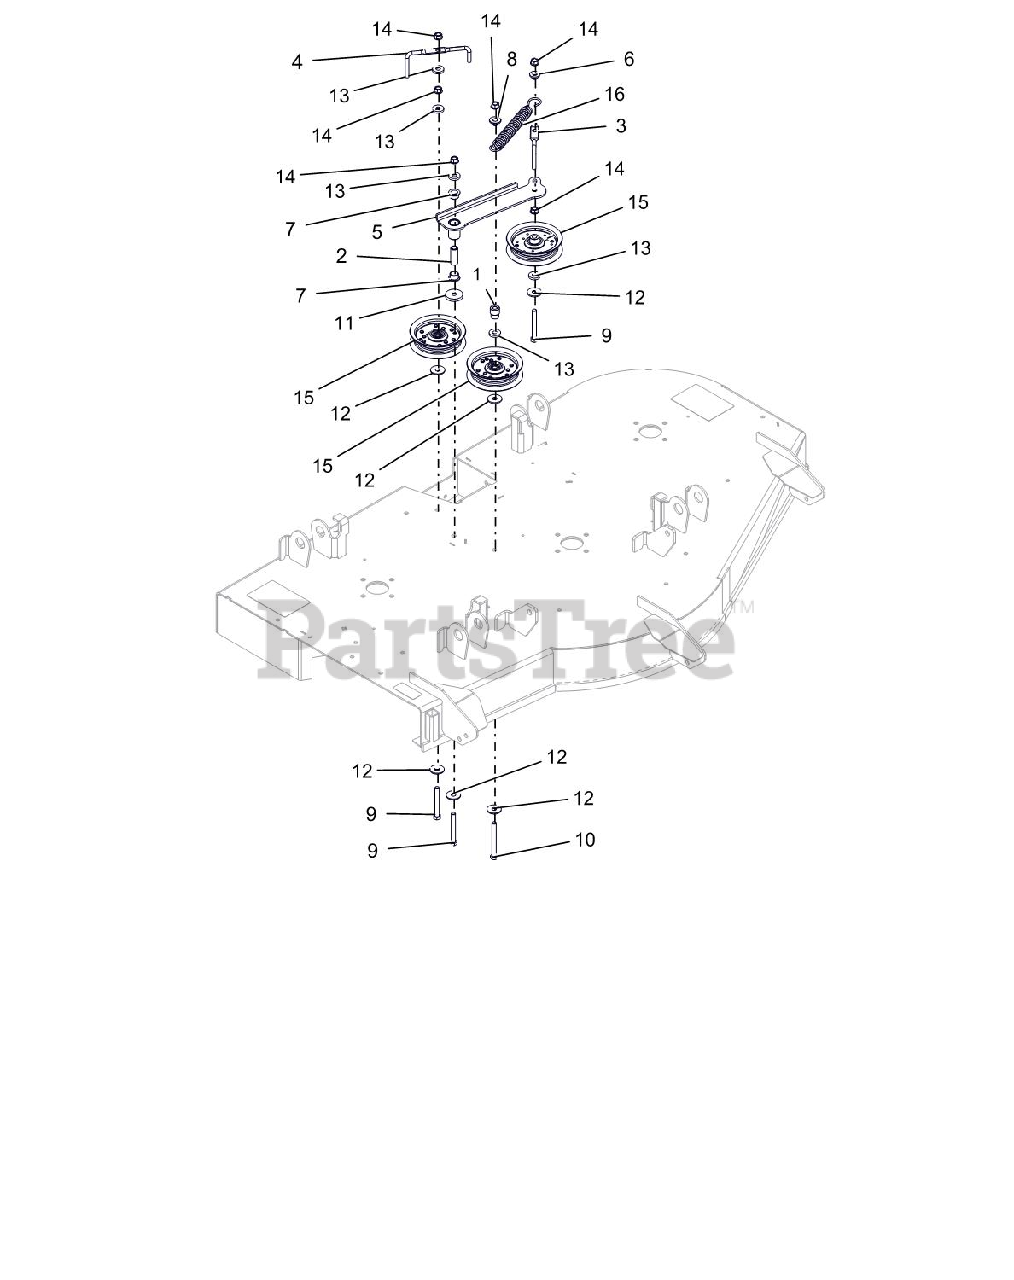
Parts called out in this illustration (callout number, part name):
1	BUSHING, IDLER (P/M)
2	SPACER, .375IDX.625ODX1.66 PM
3	WIREFORM, BELT FINGER
4	BELT FINGER
5	WLDMT, IDLER ARM-52"
6	BSHG-FLG .385X.500X.875X.406
7	BSHG-FLG, .625X.750X.500X1.00
8	BSHG-FLG .385X.500X.875X.31
9	BLT-HEX .38-16X3.00 GR5 FTH YZ
10	@BLT-HEX .38-16X3.50 GR5 YWZC
11	WSHR,FLT STL.406X1.50X.245YWZC
12	@WSHR-FL-STL .406X1.25X.10 ZC
13	WSHR-FL-STL .406X1.00X.188 YWZ
14	@NUT-LK-TOP-FLG .38-16 YWZC
15	ASM, IDLER 4"
16	SG-TENS .135X.98X6.0 WLD 62
